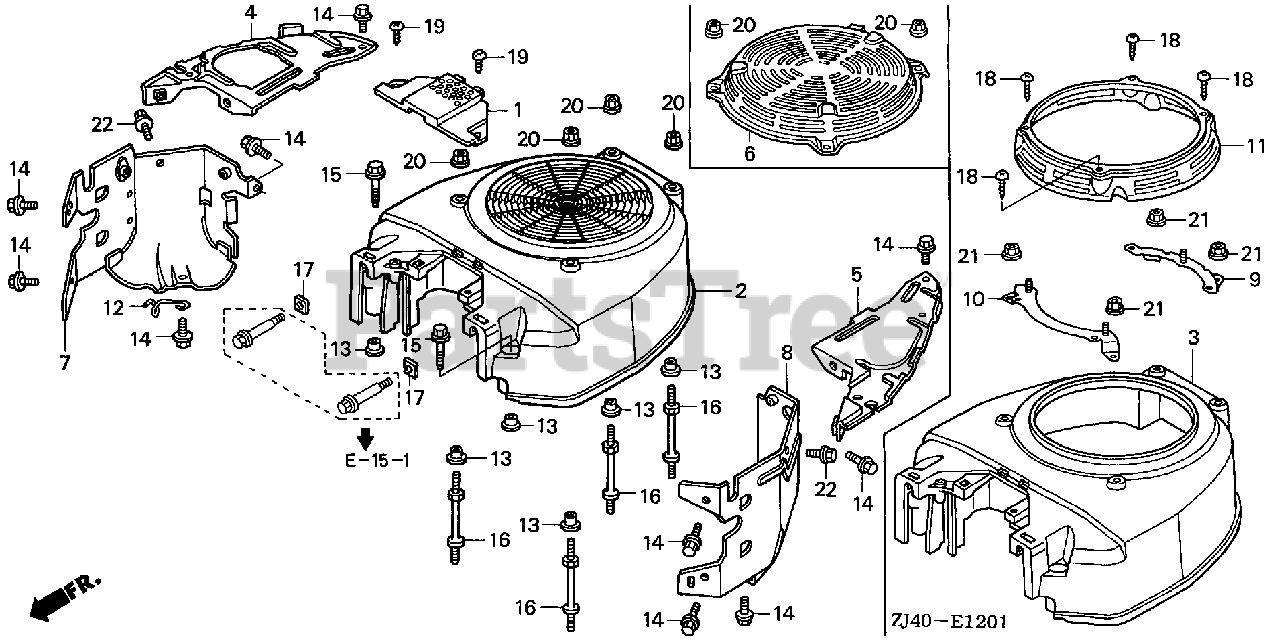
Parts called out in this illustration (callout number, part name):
1	COVER, FUEL PUMP
3	COVER, FAN *NH1* (RECOIL STARTER) (BLACK)
3	COVER, FAN *R8* (RECOIL STARTER) (BRIGHT RED)
4	PLATE, R. SIDE
5	PLATE, L. SIDE
7	SHROUD, R.
8	SHROUD, L.
9	STAY A, RECOIL STARTER
10	STAY B, RECOIL STARTER
11	COVER, RECOIL STARTER STAY *NH1* (BLACK)
11	COVER, RECOIL STARTER STAY *R8* (BRIGHT RED)
11	COVER, RECOIL STARTER STAY *R280* (POWER RED)
12	CLAMP, IGNITION TUBE
13	COLLAR B, TAILLIGHT
14	BOLT, FLANGE (6X12) (CT200)
15	BOLT, FLANGE (6X23)
16	BOLT, STUD (6X71)
17	NUT, SQUARE (5MM)
18	SCREW, TAPPING (5X16)
19	SCREW, TAPPING (5X20)
21	NUT, FLANGE (6MM)
22	BOLT, FLANGE (6X8)
